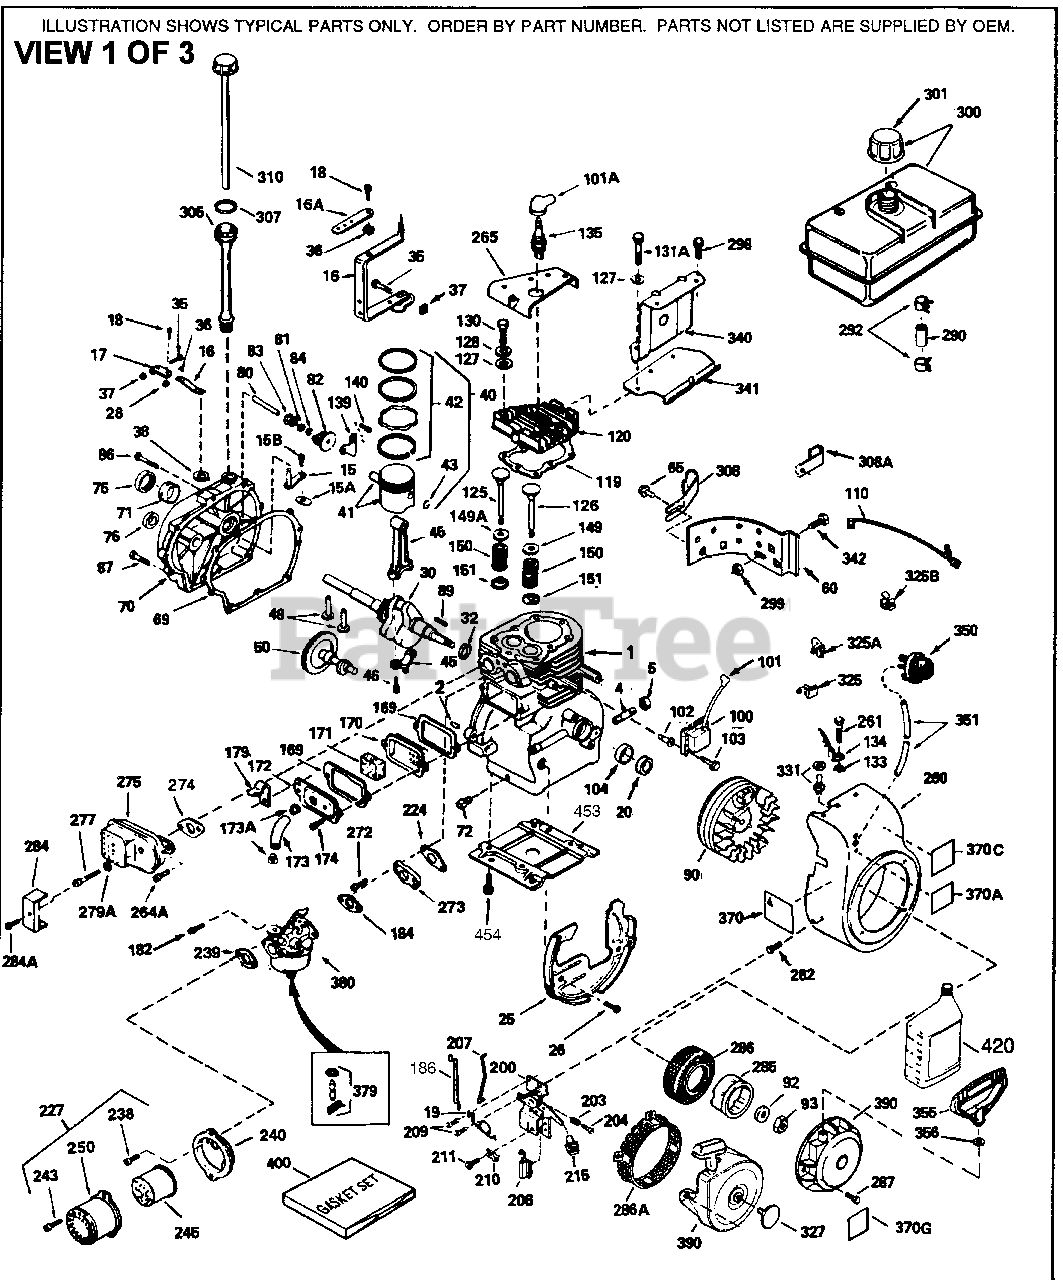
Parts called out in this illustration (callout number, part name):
1	"Cylinder (Incl. 2, 20 & 72)
2	Dowel Pin
15	Governor Rod (Incl. 15A & 15B)
15A	Governor Yoke
15B	Screw, 6-40 x 5/16"
16	Governor Lever
17	Governor Lever Clamp
18	Screw, 8-32 x 5/16"
19	Speed Control Spring
20	Oil Seal
25	Blower Housing Baffle
26	Screw, 1/4-20 x 5/8"
28	Lock Nut, 8-32
30	Crankshaft
35	Screw, 10-32 x 3/4"
36	Lock Washer #8
37	Lock Nut, 10-32
38	Retaining Ring
40	Piston, Pin & Ring Set (Std.)
40	Piston, Pin & Ring Set (.010" OS)
40	Piston, Pin & Ring Set (.020" OS)
41	Piston & Pin Ass'y. (Std.) (Incl. 43)
41	Piston & Pin Ass'y. (.010" OS) Incl. 43
41	Piston & Pin Ass'y. (.020" OS) Incl. 43
42	Ring Set (Std.)
42	Ring Set (.010" OS)
42	Ring Set (.020" OS)
43	Piston Pin Retaining Ring
45	Connecting Rod Ass'y. (Incl. 46)
46	Connecting Rod Bolt
48	Valve Lifter
50	Camshaft (BCR)
60	Blower Housing Extension
65	Screw, 10-24 x 1/2"
69	* Cylinder Cover Gasket
70	Cylinder Cover Incl. 74, 75, 80, 175 & 176
71	Crankshaft Bushing
72	Oil Drain Plug (Sq. hd., 1/4-18)
75	Oil Seal
80	Governor Shaft
82	Governor Gear Ass'y. (Incl. 81)
83	Governor Spool
84	Retaining Ring
86	Screw, 1/4-20 x 1"
87	Screw, 1/4-20 x 1-1/2"
89	Flywheel Key
90	Flywheel
92	Belleville Washer
93	Flywheel Nut
100	Solid State Ignition
101	Spark Plug Cover
102	Solid State Mounting Stud
103	Screw, Torx T-15, 10-24 x 1"
110	Ground Wire
119	* Cylinder Head Gasket
120	Cylinder Head
125	Exhaust Valve (Std.)(Incl. 151)
125	Exhaust Valve (1/32" OS) (Incl. 151)
126	Intake Valve (Std.) (Incl. 151)
126	Intake Valve (1/32" OS) (Incl. 151)
128	Belleville Washer
129	Screw, 5/16-18 x 2"
130	Screw, 5/16-18 x 2-1/4"
135	Resistor Spark Plug - RJ17LM
139	Governor Gear Bracket
140	Screw, Torx T-25, 10-24 x 1/2"
149	Valve Spring Cap
150	Valve Spring
151	Valve Spring Keeper
169	* Valve Cover Gasket
170	Breather Body
171	Breather Element
172	Valve Cover
173	Breather Tube
173A	Breather Tube Grommet
174	Screw, 10-24 x 1/2"
179	Retainer Clip
182	Screw, 1/4-20 x 27/32"
184	* Carburetor To Intake Pipe Gasket
186	Governor Link
200	Control Bracket (Incl.19,203,204,206)
203	Compression Spring
204	Screw, 5-40 x 7/16"
206	Terminal
207	Throttle Link
209	Screw, 10-32 x 1/2"
224	* Intake Pipe Gasket
227	A/C Elbow Incl. items marked with # s ign
228	# Stud, 1/4-20 x 6.20
229	# Nut & Lock Washer, 1/4-20
235	Air Cleaner Elbow Fitting
238	Screw, 10-32 x 7/8"
239	Air Cleaner Gasket
242	# Air Cleaner Base
245	Air Filter
250	Air Cleaner Cover
260	Blower Housing
262	Screw, T-40, 5/16-24 x 21/32"
265	Cylinder Head Cover
269	* Exhaust Manifold Gasket
272	Screw, 5/16-18 x 3/4"
273	Carburetor Flange (Incl. 182)
275	Muffler
285	Starter Cup
287	Screw, 8-32 x 1/2"
290	Fuel Line
292	Fuel Line Clamp
298	Screw, 1/4-15 x 3/4"
300	Fuel Tank (Incl. 292 & 301)
301	Fuel Cap (Red)
305	Oil Fill Tube
307	"O" Ring
308	Fill Tube Clip
310	Dipstick
327	Starter Plug
340	Fuel Tank Bracket
341	Fuel Tank Bracket
342	Screw, 1/4-20 x 5/8"
370	Instruction Decal
370A	Decal - XL/C Industrial/Commercial
370C	Decal - Important Lubrication - SAE 3
380	Carburetor (Incl. 184)
390	Rewind Starter
400	* Gasket Set (Incl. items marked PK in notes) Incl. part #'s 27272A (2), 278 96A (2), 27913A (1), 27915A (2), 2893 8C (1), 29673 (1), 30684 (1), 31688A (1), 33355A (1), 35865 (1)
420	SAE 30 4-Cycle Engine Oil (Quart)
453	Engine Mounting Base
454	Screw, 5/16-18 x 3/4"
